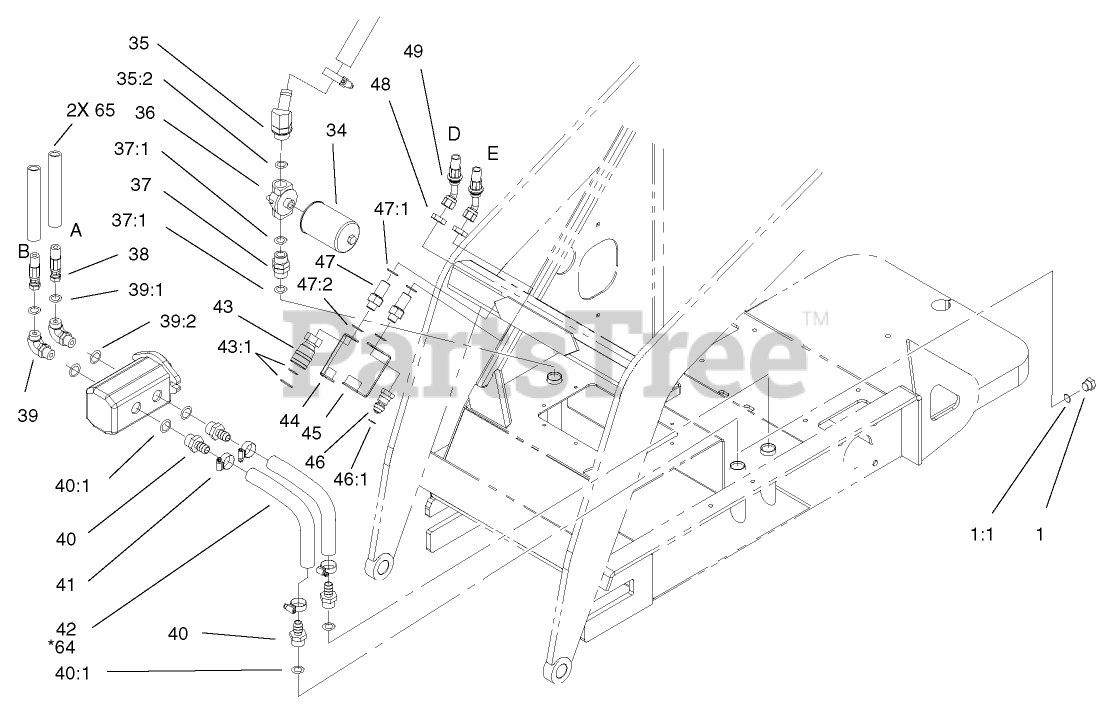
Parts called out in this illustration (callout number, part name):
1	PLUG-HEX
1:1	O-RING
34	FILTER-OIL, TRANSMISSION
35	ELBOW-45 DEG
35:2	O-RING
36	HEAD-FILTER
37	FITTING-THREAD, STRAIGHT
37:1	O-RING
38	HOSE-HYD
39	FITTING-ELBOW 90
39:1	O-RING
39:2	O-RING
40	FITTING-STRAIGHT
40:1	O-RING
41	CLAMP-HOSE
42	HOSE-SUCTION, HYD
43	COUPLER-FACE, FLUSH
43:1	KIT-SEAL
44	CAP-DUST, COUPLER
45	CAP-DUST, NIPPLE
46	NIPPLE-FACE, FLUSH
46:1	SEAL KIT
47	FITTING-ADAPTER, BULKHEAD
47:1	O-RING
47:2	O-RING
48	NUT-LOCK, BULKHEAD
49	HOSE-HYD
64	Spring-Compression
65	SLEEVE-GUARD, HOSE
